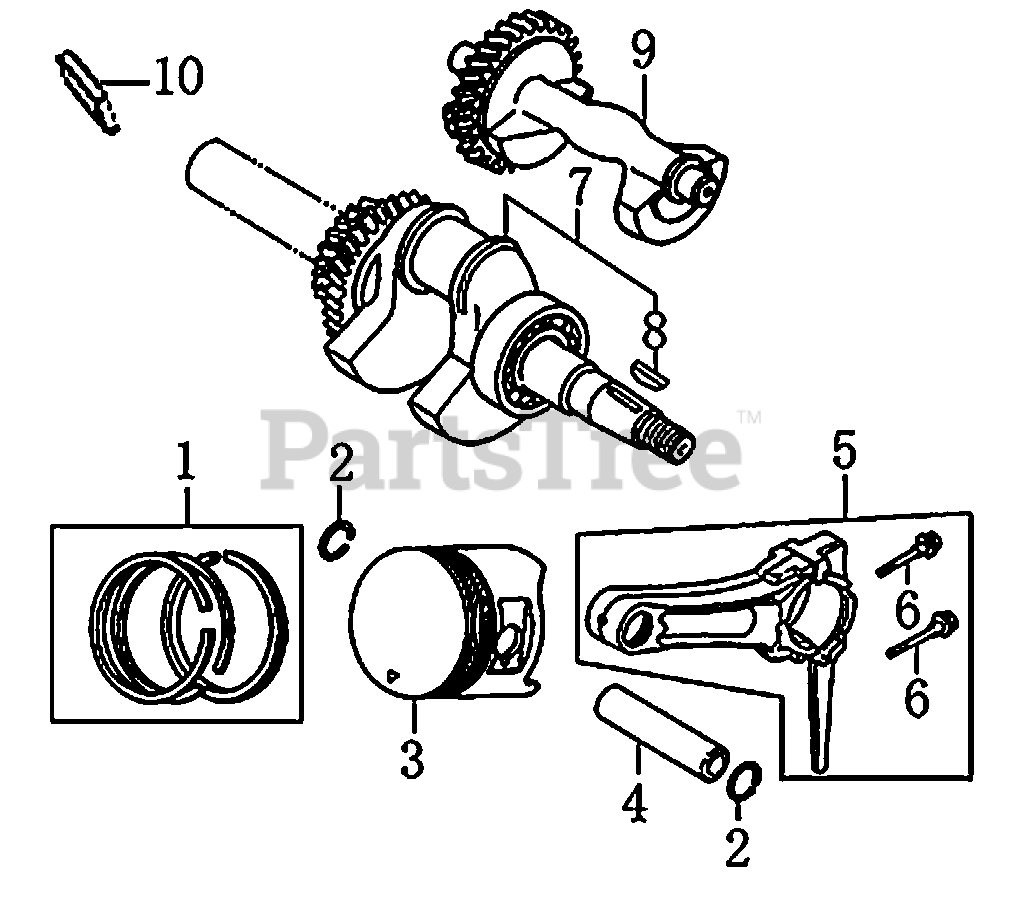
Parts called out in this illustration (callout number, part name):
1	RING SET, PISTON
2	CLIP, PISTON PIN
4	PIN, PISTON
5	CONNECTING ROD ASSY
6	BOLT, CONNECTING ROD
7	CRANKSHAFT ASSY
8	KEY, SPECIAL WOODRUFF
9	WEIGHT, BALANCER
10	KEY, CRANKSHAFT
